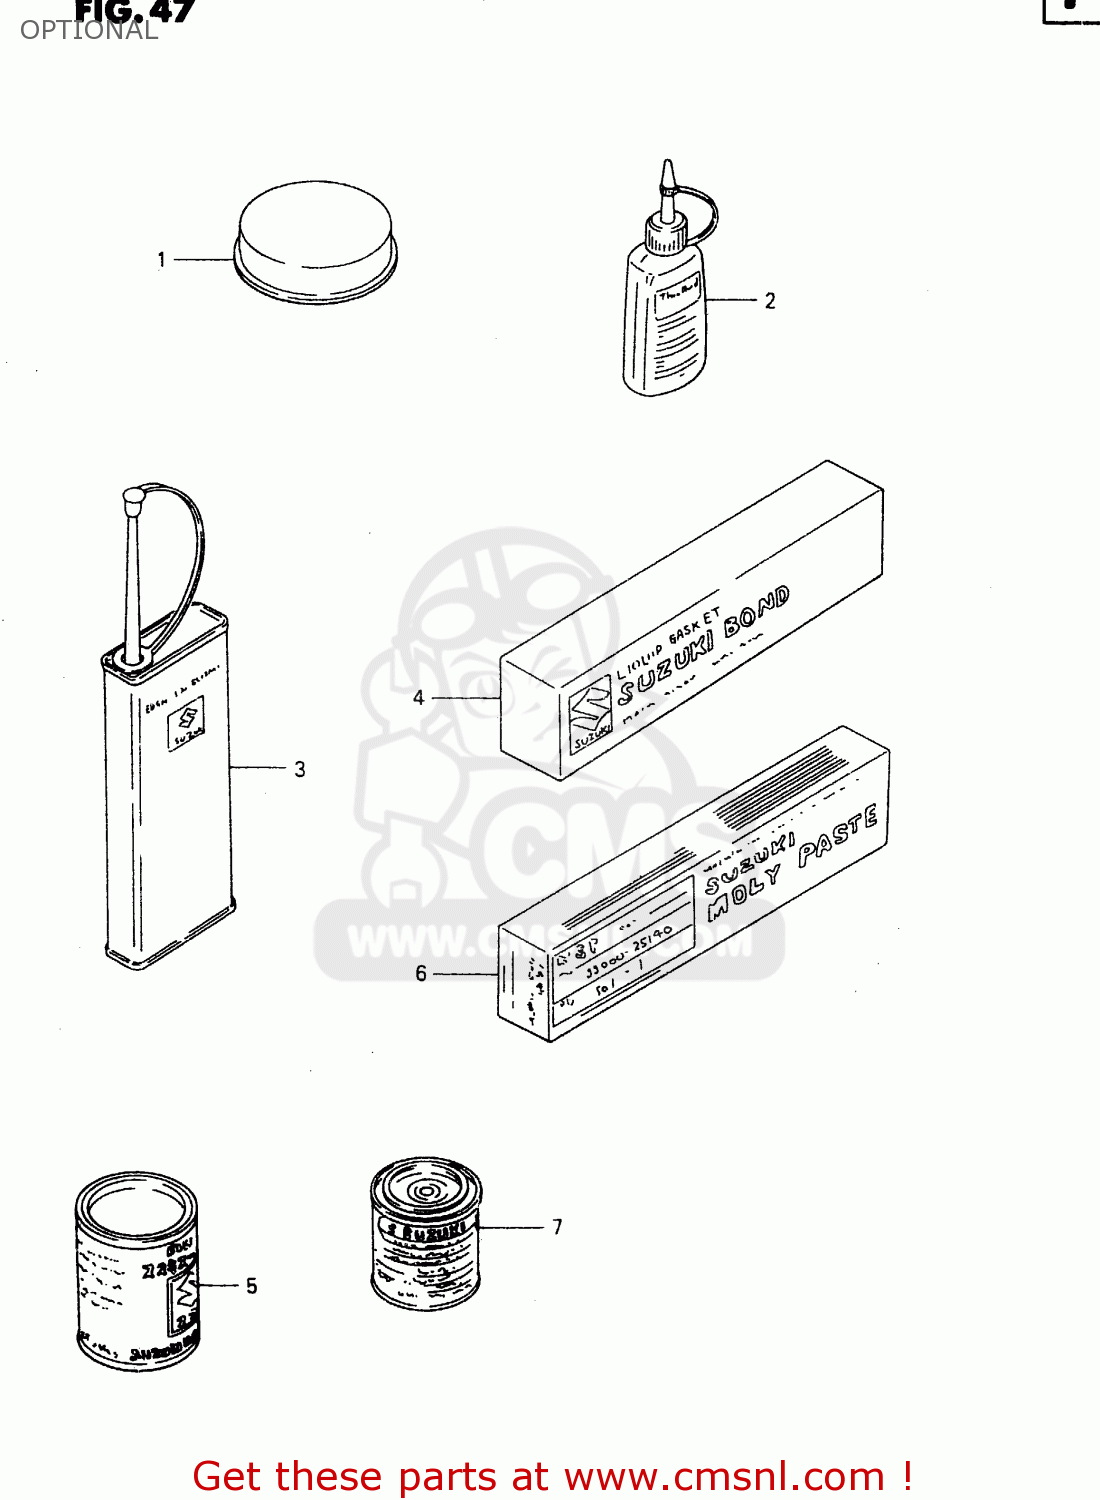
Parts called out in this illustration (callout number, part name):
1	GREASE,PBC FOR BRK PAD 20G
2	THREAD LOCK NO.1342
3	THREAD LOCK NO.1401 CLEAR 200G
4	LIQUID GSKT NO.1215 250G
5	GREASE(C)EP2 LITHIUM 150G
6	SUZUKI MOLY PASTE
7	PAINT,BLACK
